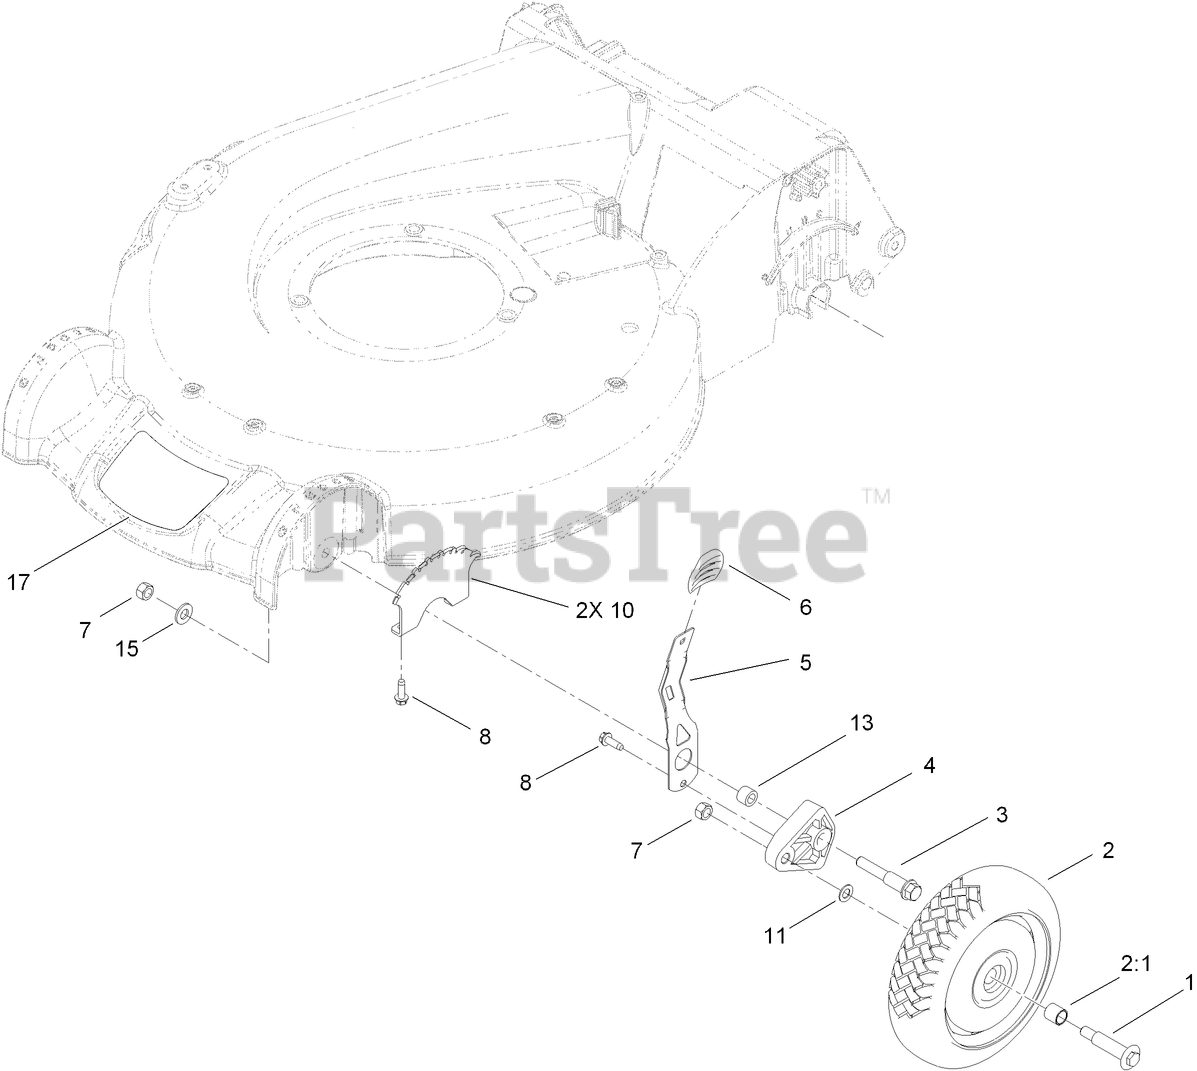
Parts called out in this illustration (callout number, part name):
1	BOLT-SHOULDER
2:1	BUSHING
3	SCREW-SHOULDER
4	ARM-PIVOT
5	ARM-SPRING
6	KNOB-LEVER, HOC
7	LOCKNUT
8	SCREW-HWHTF
10	PLATE-HOC
11	WASHER
13	SPACER-WHEEL
15	WASHER-FLAT
17	DECAL-HOUSING
